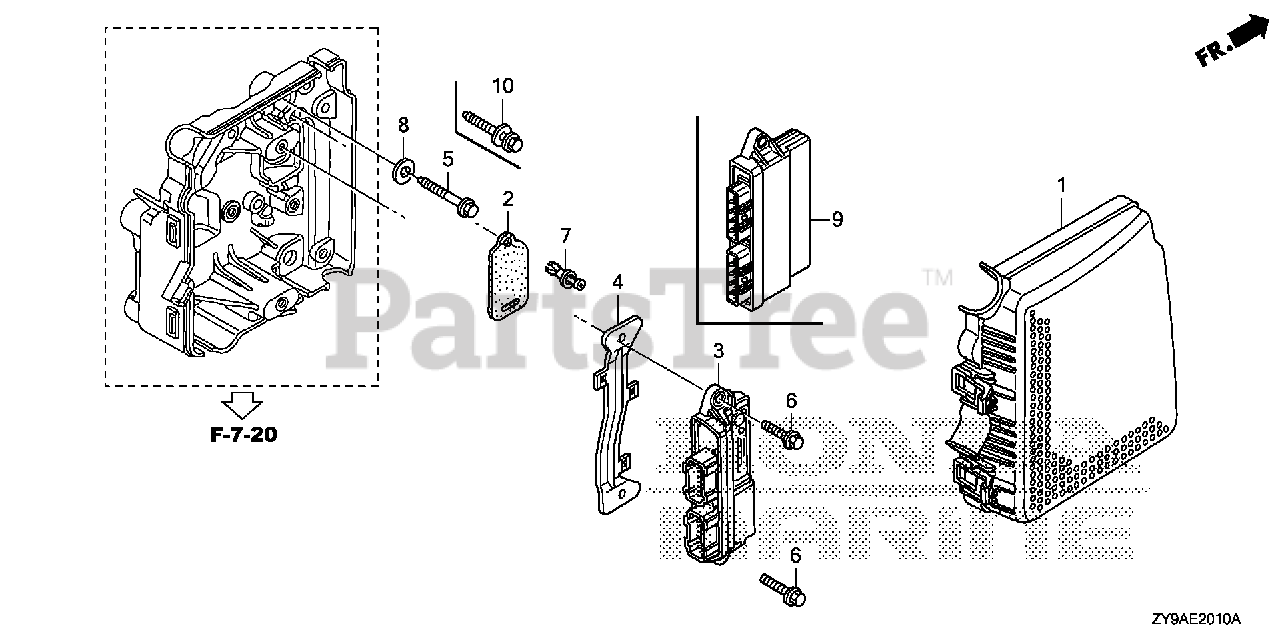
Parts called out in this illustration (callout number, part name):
4	BRACKET, ELECTRONIC CONTROL UNIT
6	BOLT, FLANGE (6X20)
6	BOLT, TORX (M6X20)
9	CONTROL UNIT, ELECTRONIC
10	BOLT-WASHER (6X27) (CT200)
